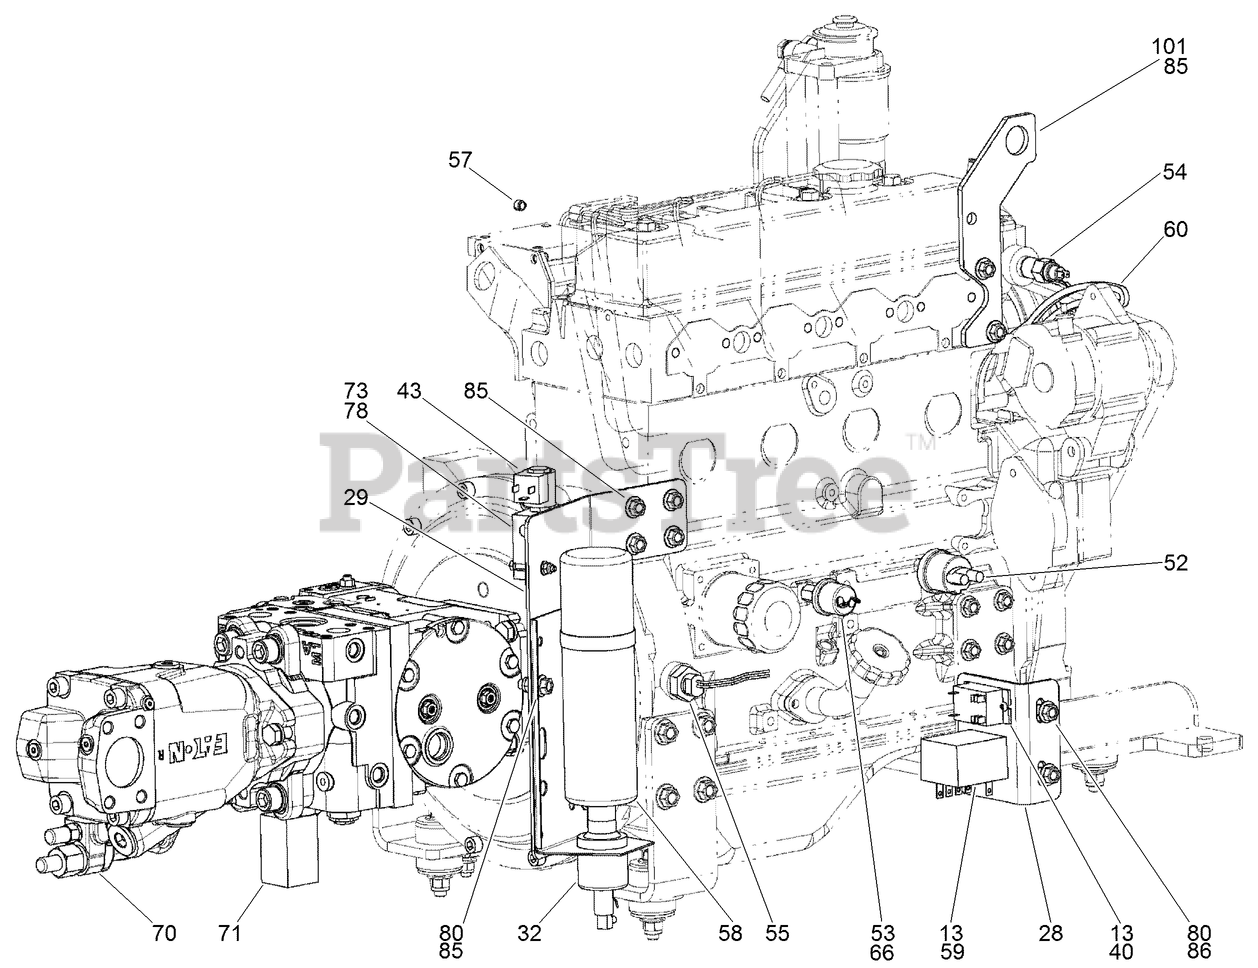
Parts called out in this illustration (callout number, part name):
13	SCREW - PHd Type 1 #10 - 24 x .500 CST ZND
28	BRACKET - Relay
29	MOUNT - Cold Start
32	KIT - Cold Start
40	RELAY - 2 Pole 12 VDC Panel Mount
43	VALVE - Dir, Cart, 3W2P, SOL, 12VDC
52	SENSOR-PRESSURE, OIL
53	SENSOR-PRESSURE, OIL
54	SENSOR-COOLANT
55	SENSOR-RPM, MAG PICKUP
57	ATOMIZER - Ether Start
58	BOTTLE - Ether
59	RELAY-CONTROL, ENGINE
60	BRACKET-Alternator
66	ADAPTER - Pipe
70	PUMP - Hydraulic, Load Sense (Serial Numbers DD202480145 and Prior)
70	HYD LOAD SENSE PISTON PUMP ASM
71	HYD HYDROSTAT PUMP ASM
73	SCREW, METRIC FLANGE w/BODY - M6 x 45
78	NUT, METRIC FLANGE PREVAILING - M6 Zinc
80	NUT-FLANGE, NYLOCK
85	SCREW-FLANGE
86	SCREW-HH
101	PLATE-HOIST POINT
